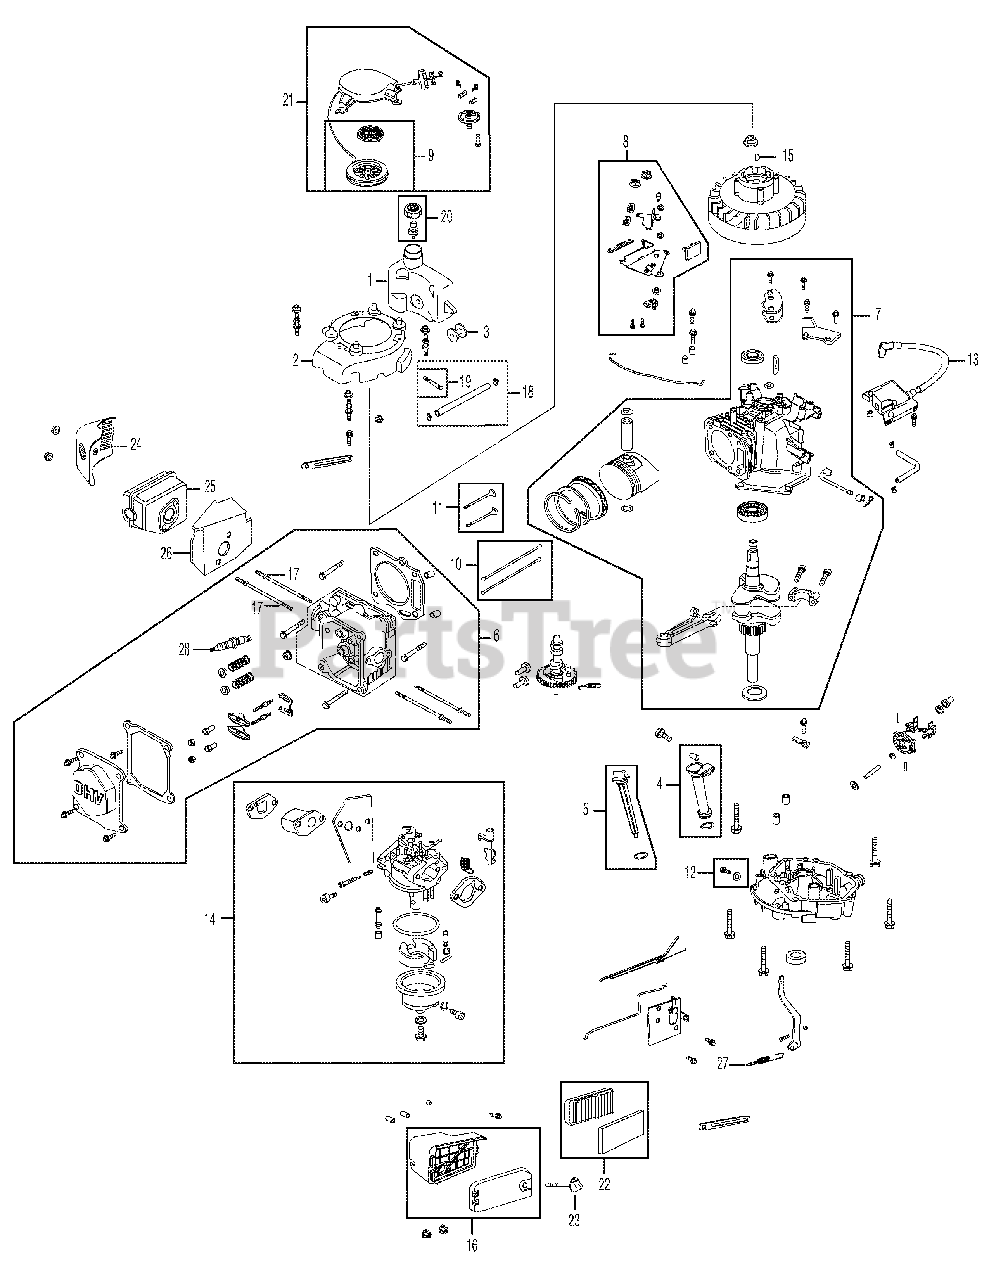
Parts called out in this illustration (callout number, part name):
1	Fuel Tank
2	Flywheel Shroud
2	Screw
3	Rubber Fuel Tank Mounting Washer
4	Oil Filler Tube Assembly
5	Dipstick Assembly
6	Cylinder Head Complete
7	Short Block Assembly
8	Stop Swtich and Brake Assembly
9	Recoil Spring and Pulley Assembly
10	Push Rod Kit
11	Valve Kit
12	Oil Drain Plug and Washer Assembly
13	Ignition Coil
14	Carburetor Assembly
15	Flywheel Key
16	Air Cleaner Housing Assembly Complete
17	Muffler Stud Assembly
18	Fuel Line Kit
19	Fuel Filter
20	Fuel Cap Assembly
21	Recoil Starter Assembly
22	Air Cleaner Kit
23	Air Cleaner Thumb Screw
24	Muffler Guard
25	Muffler
26	Muffler Gasket & Heat Shield
27	Governor Return Spring
28	Spark Plug
